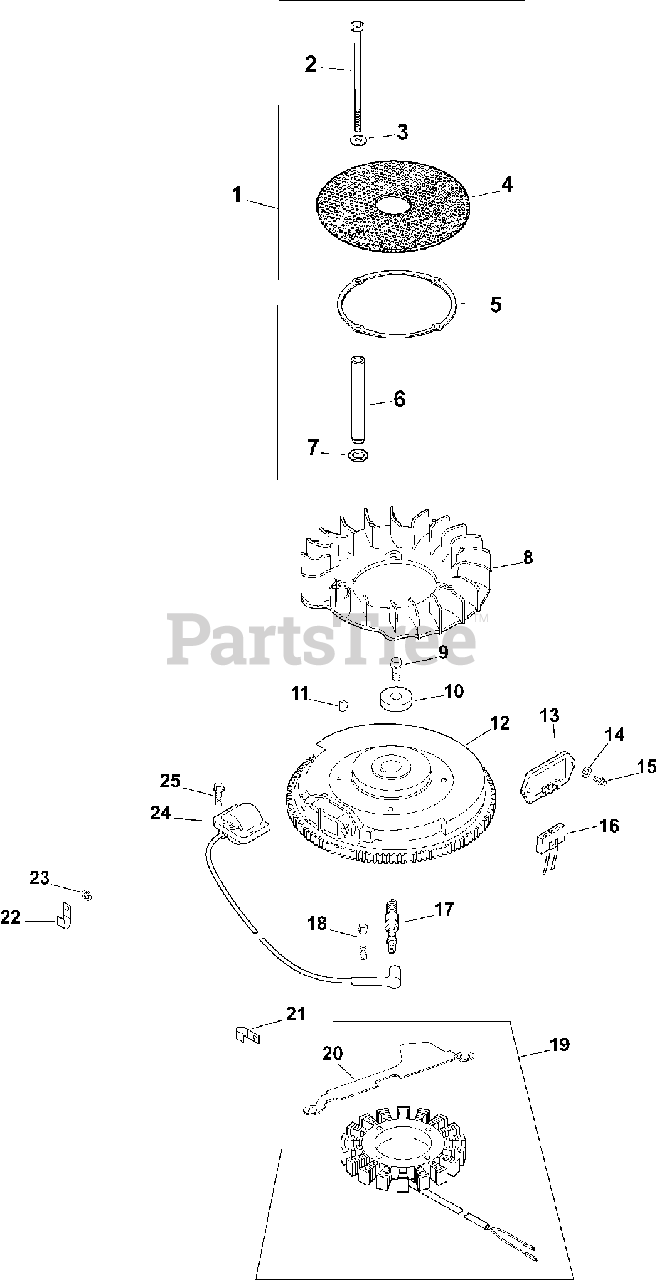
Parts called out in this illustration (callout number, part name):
1	KIT, CHOPPER SCREEN
2	SCREW, CAP M6X1.0X99.5
3	WASHER, FLAT 1/4" (O.D. 5/8")
4	SCREEN, GRASS-USE 24 162 41-S
5	RING, SUPPORT USE 25 141 08-S
7	WASHER, SPRING 10 MM
8	FAN (DOMED)-USE 24 157 17-S
9	SCREW, FLG M10X1.5X45 - (#25086361S)
10	WASHER, FLAT 13/32"
11	KEY, 3/16" X 5/8"
13	REG/RECT-15 AMP (KM)-USE 41 403 10-S
14	WASHER, FLAT 3/16"
15	SCREW, PHL HD #11-16X7/8"
16	CONNECTOR, BODY (KM)-USE 25 155 41-S
17	PLUG, SPARK (PRO SERIES)
18	SCREW, M5X0.8X25 - (#25086402S)
19	STATOR KIT - USE 237878-S
20	BRACKET, STATOR WIRE
22	CLIP, CABLE
23	WASHER, FLAT 1/4" (O.D. 1/2")
24	MODULE, IGNITION-USE 24 584 45-S
25	SCREW, FLG THD FRM M5X.8X20-(#25086399S)
